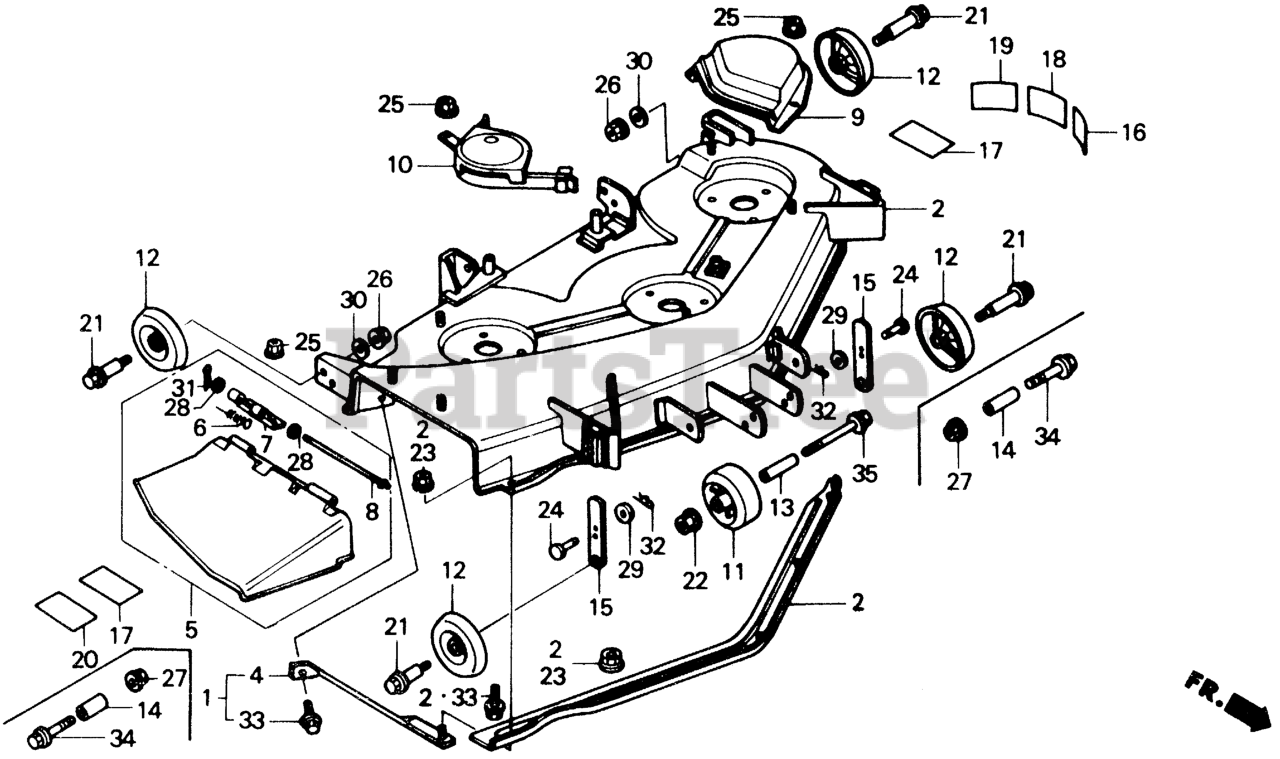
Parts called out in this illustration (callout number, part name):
1	BAR KIT, SAFETY (46") (NOT AVAILABLE)
2	HOUSING, CUTTER
3	PLATE, PROTECTOR *NH35M* (CLOUD SILVER METALLIC) (NOT AVAILABLE)
4	BAR, SAFETY
5	ADAPTER, DISCHARGE
6	SPRING, DISCHARGE ADAPTER
7	HINGE, DISCHARGE ADAPTER
8	PIN, DISCHARGE ADAPTER
9	COVER, L. BELT
10	STOPPER, BELT
11	ROLLER, ANTI-SCALP
12	ROLLER, ANTI-SCALP
13	COLLAR, ANTI-SCALP ROLLER
14	COLLAR, ANTI-SCALP ROLLER (12.7X15.9X39.5)
15	ARM, ROLLER (12MM)
16	MARK, HEIGHT OPERATION (ENGLISH)
17	LABEL A, WARNING (ENGLISH)
18	MARK, INCH SIZE (46)
20	MARK, DANGER
21	BOLT, ANTI-SCALP ROLLER
22	NUT, U (10MM) (FUSE RASHI)
23	NUT, FLANGE (8MM)
24	PIN, ROLLER ARM (8X22)
25	NUT, FLANGE (8MM)
26	NUT, FLANGE (10MM)
27	NUT, FLANGE (12MM)
28	WASHER, PLAIN (6MM)
31	PIN, COTTER (2.0X15)
32	PIN, SNAP (7MM)
33	BOLT, FLANGE (8X16)
34	BOLT, FLANGE (12X60)
35	BOLT, FLANGE (10X110)
